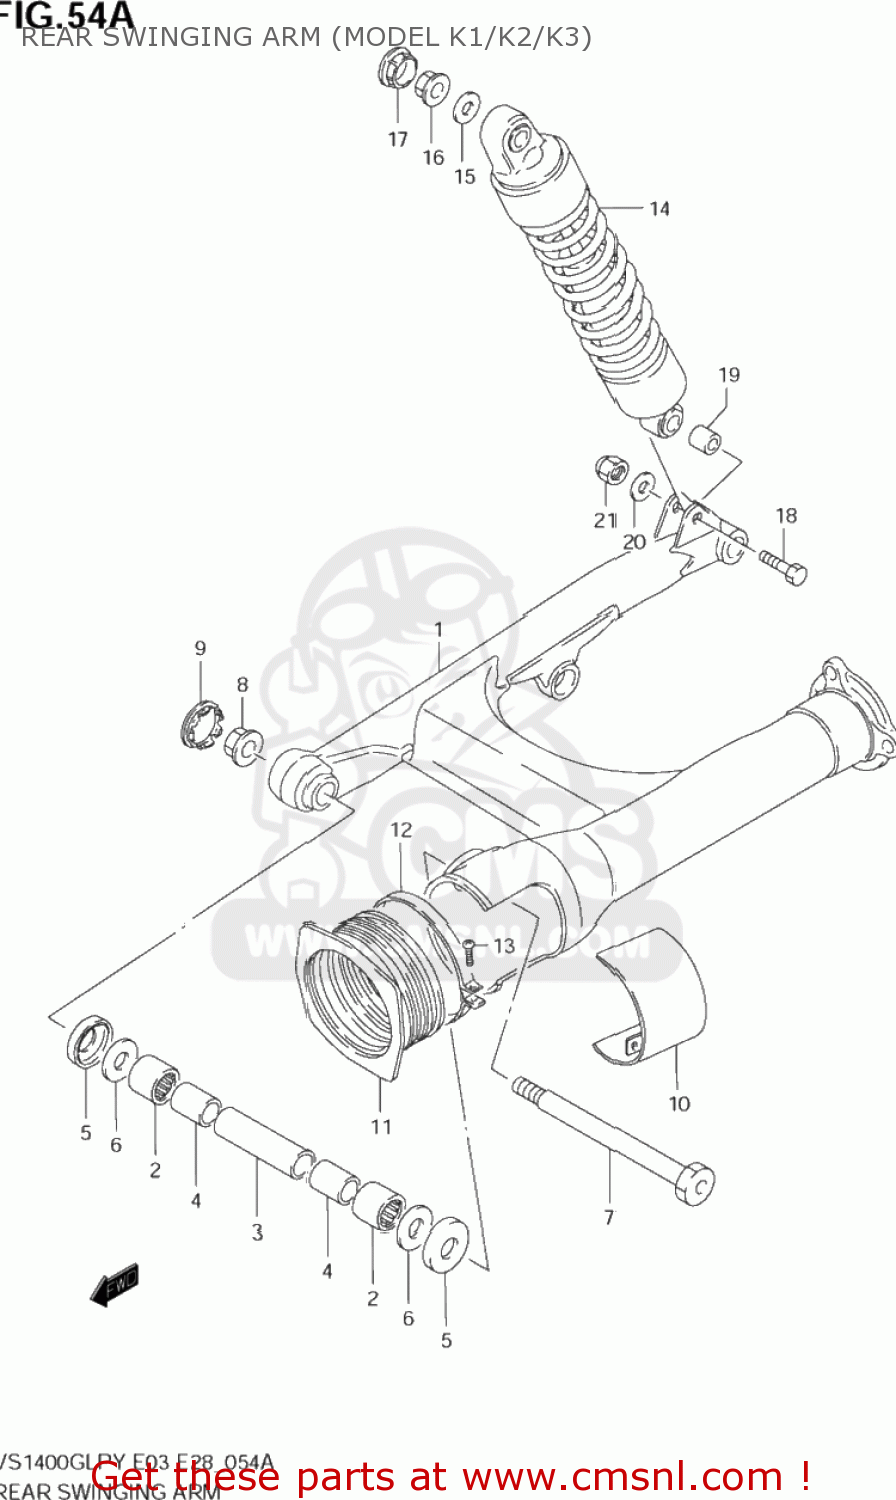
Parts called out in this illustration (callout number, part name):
1	SWINGINGARM,RR
2	BEARING(22X29X30)
3	SPACER,RR SWGARM PIVOT CTR
4	SPACER,RR SWGARM PIVOT
5	SEAL,RR SWGARM PIVOT DUST
6	WASHER
7	SHAFT,RR SWINGINGARM PIVOT
8	NUT
9	CAP,RR SWINGING ARM PIVOT,R
10	COVER,RR SWGARM PIVOT,L
11	BOOT,PROPELLER SHAFT
12	CLAMP
13	SCREW
14	ABSORBER ASSY,RR SHOCK
15	WASHER(10.5X20X2.3)
16	NUT
17	CAP,FRAME HANDLE GRIP
18	BOLT(10X39)
19	SPACER(10.2X14X20.7)
20	WASHER (10.5X24X2.3)
21	NUT
